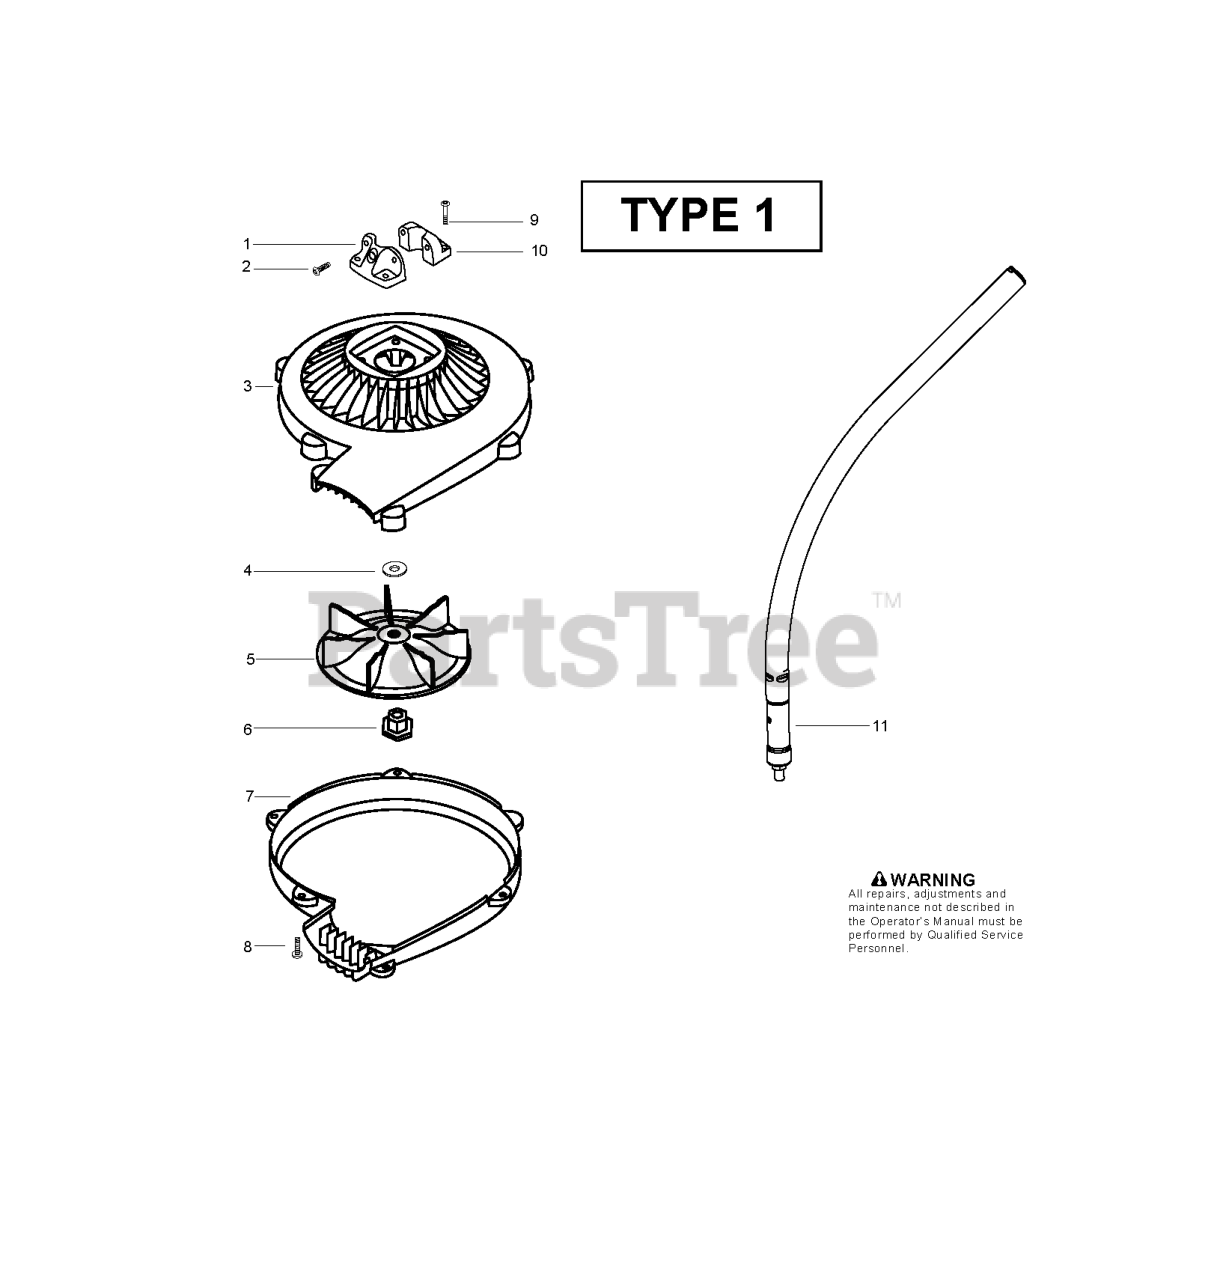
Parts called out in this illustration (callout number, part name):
1	CLAMP,RIGHT
3	HSG,BLOWER (UPPER)
6	ARBOR, IMPELLER
7	HSG, BLOWER (LOWER)
10	CLAMP,LEFT
11	DRIVE SHAFT ASSY
